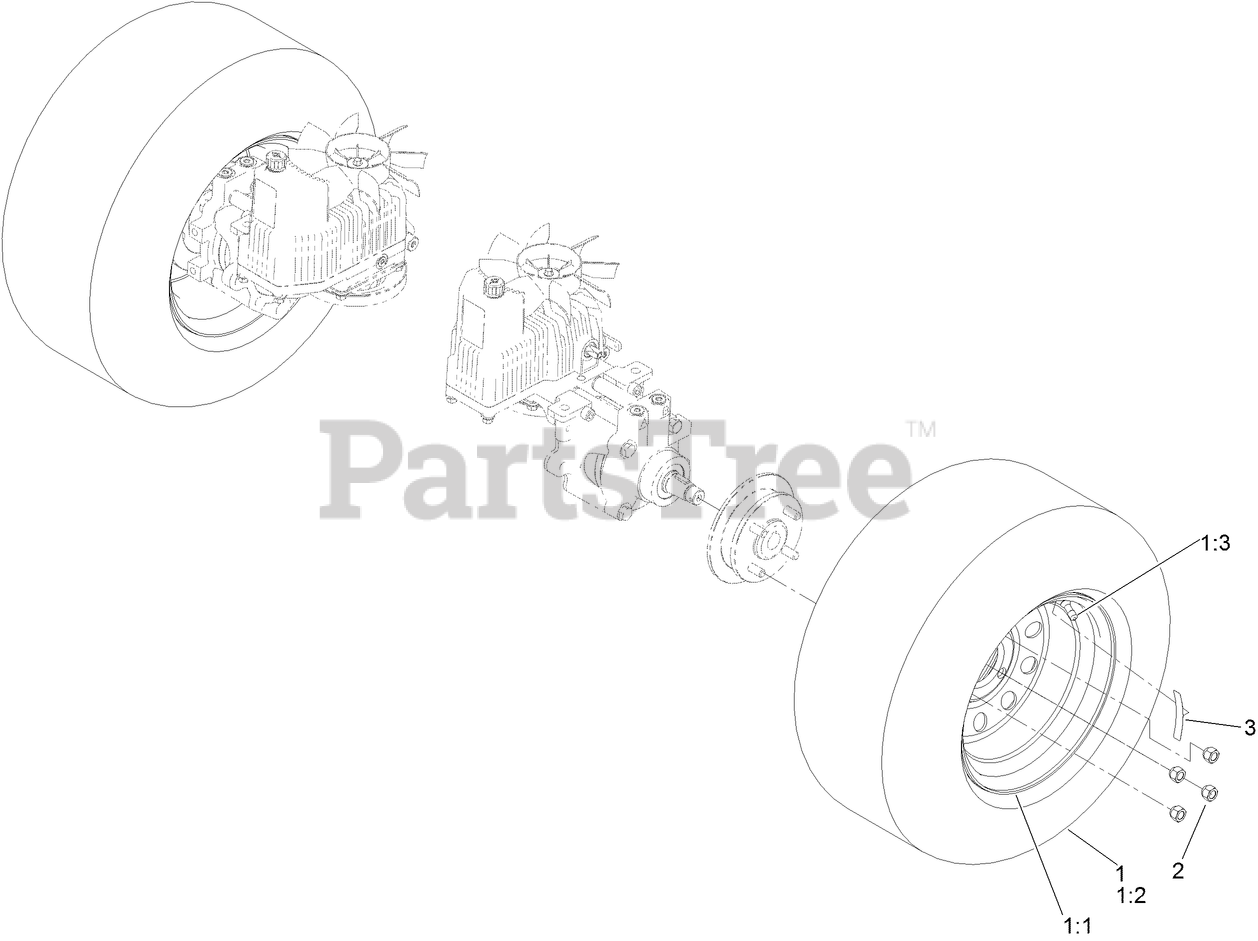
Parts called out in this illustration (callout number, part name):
1	WHEEL AND TIRE ASM
2	NUT-LUG
3	DECAL-TORQUE, WHEEL HUB LUG
